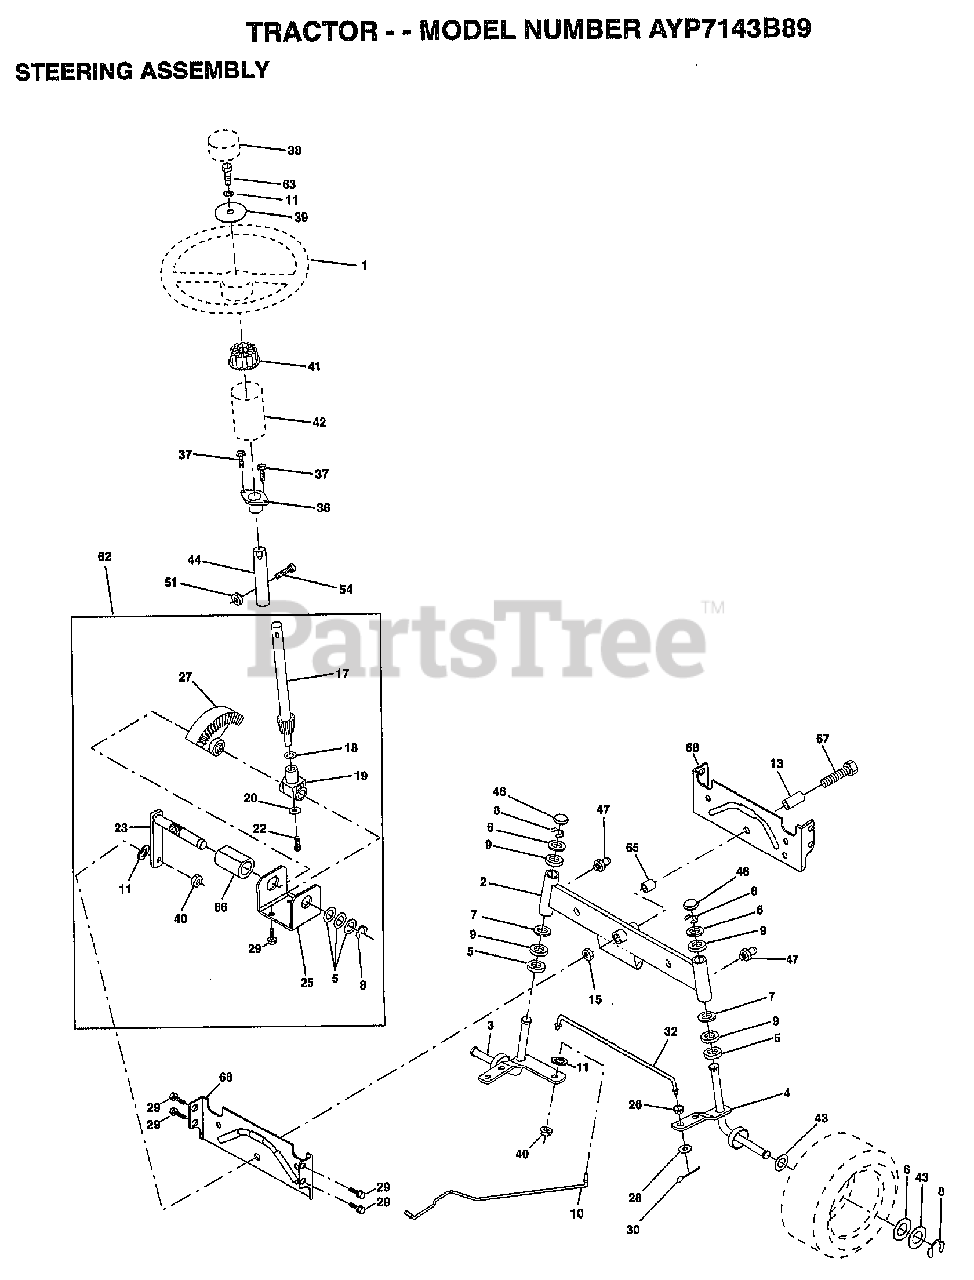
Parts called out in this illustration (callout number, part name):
1	WHEEL STR AYP BLK
2	AXLE ASM
3	SPINDLE.ASM.LH
4	"SPINDLE ASM,RH"
5	WASHER .T
6	WASHER
7	WASHER
8	RING
9	COL. SRTG. BEAR.
10	DRAGLINK-STAMPED
11	LOCKWASHER
13	BEARING AXLE
15	"NUT-LOC,FLANGE LT"
17	SHAFT ASM STEERIN
18	THRUST WASHER
19	SUPPORT.SHAFT
22	SCREW HEX SOC1/4-
25	BRKT-STEERING
26	BUSHING.DRAGLINK
27	GEAR SECTOR
28	WASHER
29	SCREW
30	COTTER PIN
32	TIE ROD
36	BUSHING.STEERING
37	"SCREW-TT,10-32 FL"
38	CAP STEER AYP
39	WASHER T
40	GRIPCO NUT
41	ADAPTER LT
42	BOOT.STEER.PL
44	EXT SHAFT STEERIN
46	CAP
47	ZERK M
51	NUT
54	BOLT
62	KIT STEERING ASM
63	BOLT
65	SPACER AXLE
66	"BEARING-ARM,PITMA"
67	BOLT
68	BRACE AXLE
